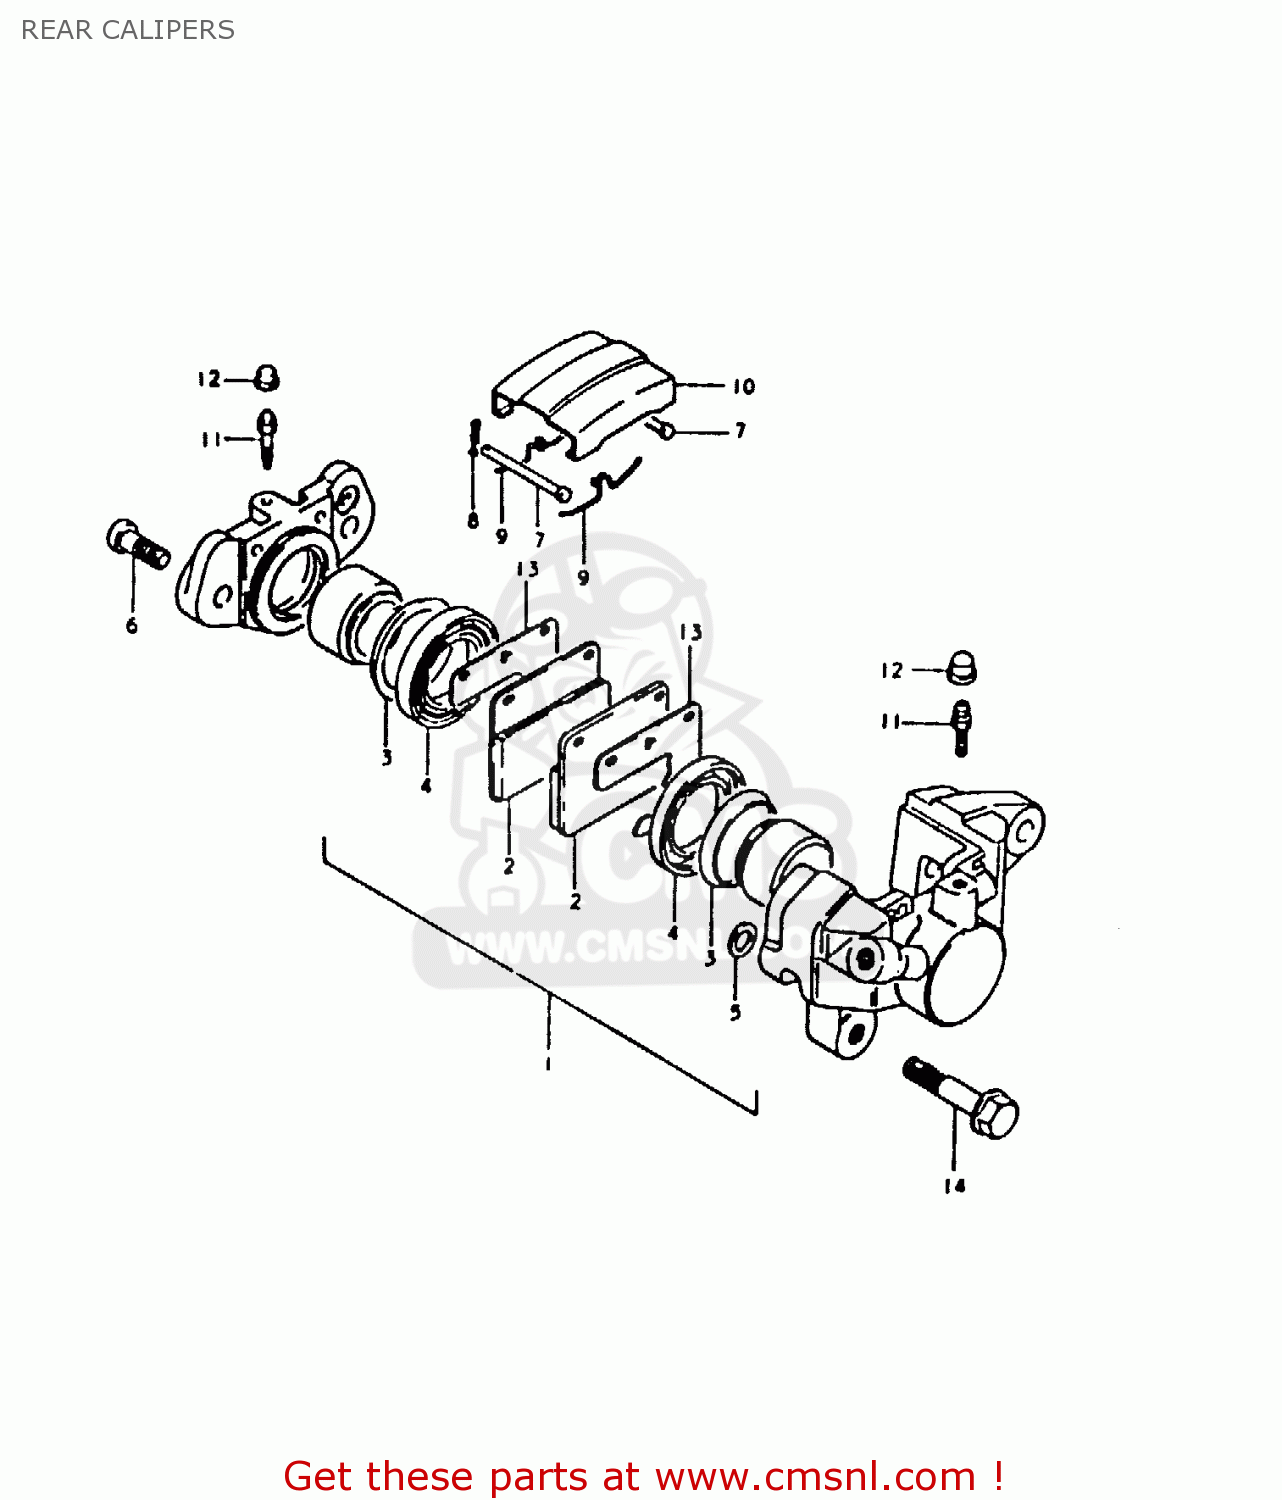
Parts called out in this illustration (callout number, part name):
1	PISTON SET
2	PAD,BRAKE
3	SEAL,PISTON
4	BOOT,PISTON
5	SEAL,PISTON
6	BOLT,HOUSING
7	PIN,PAD
8	CLIP,PAD PIN
9	SPRING
10	COVER,DUST
11	BLEEDER
12	CAP,BREATHER
13	SHIM,RR CALIPER
14	BOLT
